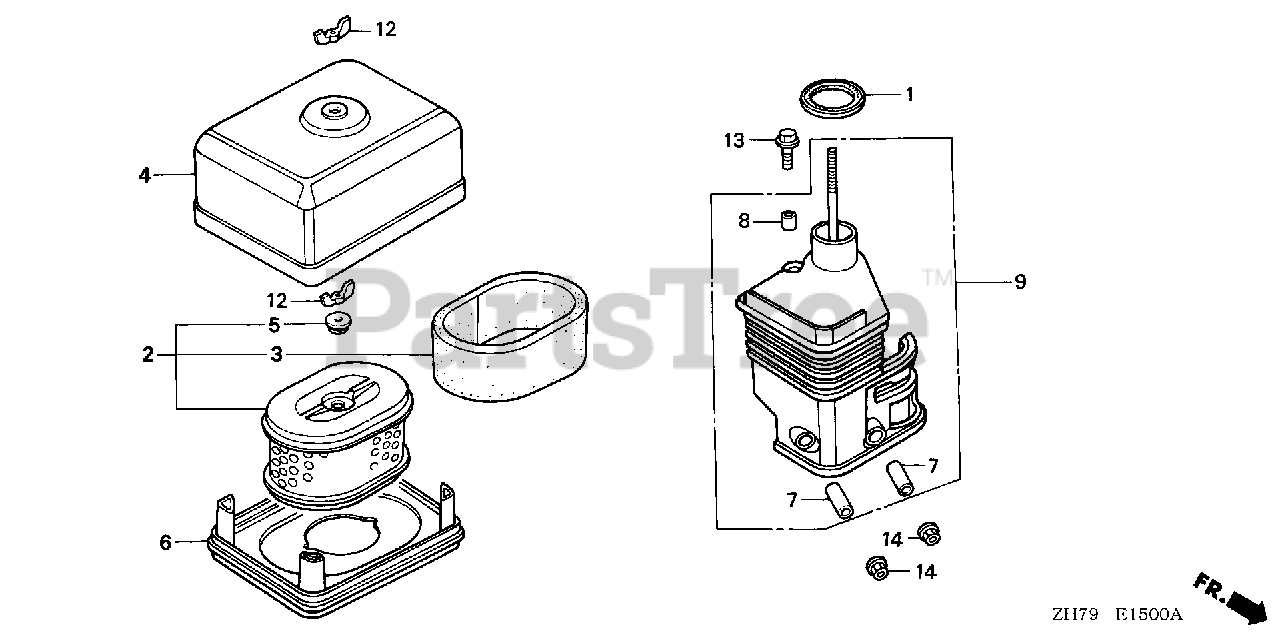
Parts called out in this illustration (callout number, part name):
1	GASKET, ELBOW
2	ELEMENT, AIR CLEANER (DUAL)
3	FILTER (OUTER)
4	COVER, AIR CLEANER (DUAL)
5	GROMMET, AIR CLEANER
7	COLLAR, AIR CLEANER
8	COLLAR B, AIR CLEANER
9	ELBOW, AIR CLEANER
12	WINGNUT, TOOL BOX SETTING
13	BOLT, FLANGE (6X20)
14	NUT, FLANGE (6MM)
